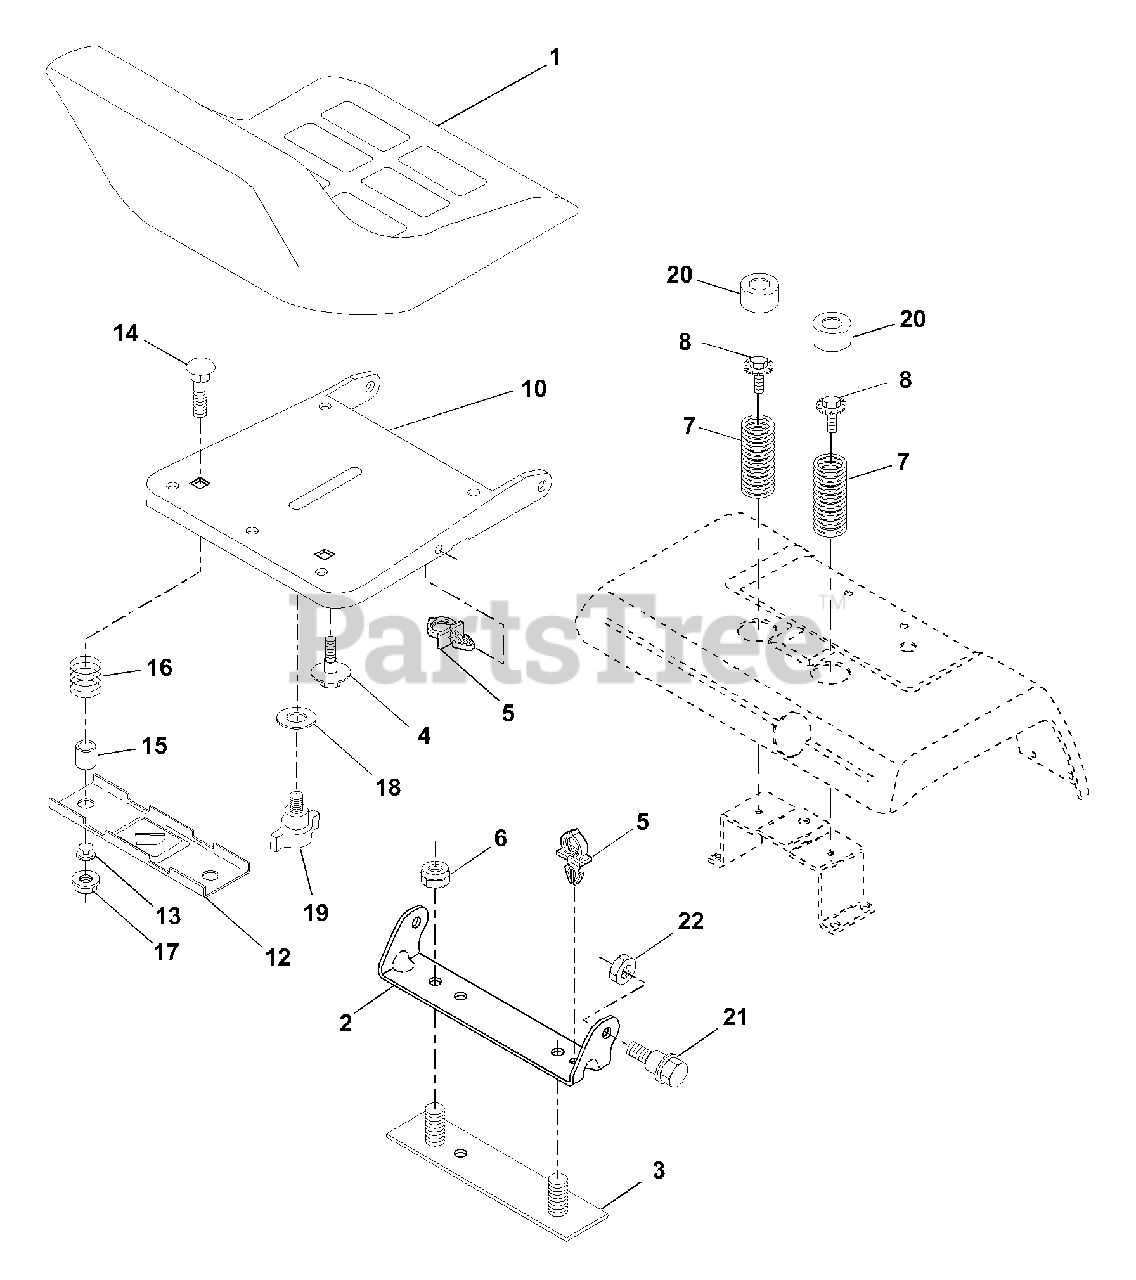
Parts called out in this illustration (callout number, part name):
1	Seat
2	Bracket, Pivot Seat
3	Strap, Fender
4	Bolt, Shoulder 5/16-18 X .62
5	Clip, Push In Hinged
6	Nut, Crownlock 3/8-16
7	Spring, Seat Cprsn
8	Bolt 5/16-18 UNC X 3/4
10	Pan, Seat
12	Bracket, Mounting Switch
13	Bushing, Snap
14	Bolt, Carriage 1/4-20 X 1-1/2
15	Spacer, Split
16	Spring, Cprsn
17	Nut, Lock 1/4 Lge Flg Gr. 5
18	Washer 17/32 X 1-3/16 X 12 Ga.
19	Knob, Seat
20	Cap, Spring Seat
21	Bolt, Shoulder 5/16-18
22	Nut, Crownlock 5/16-18
